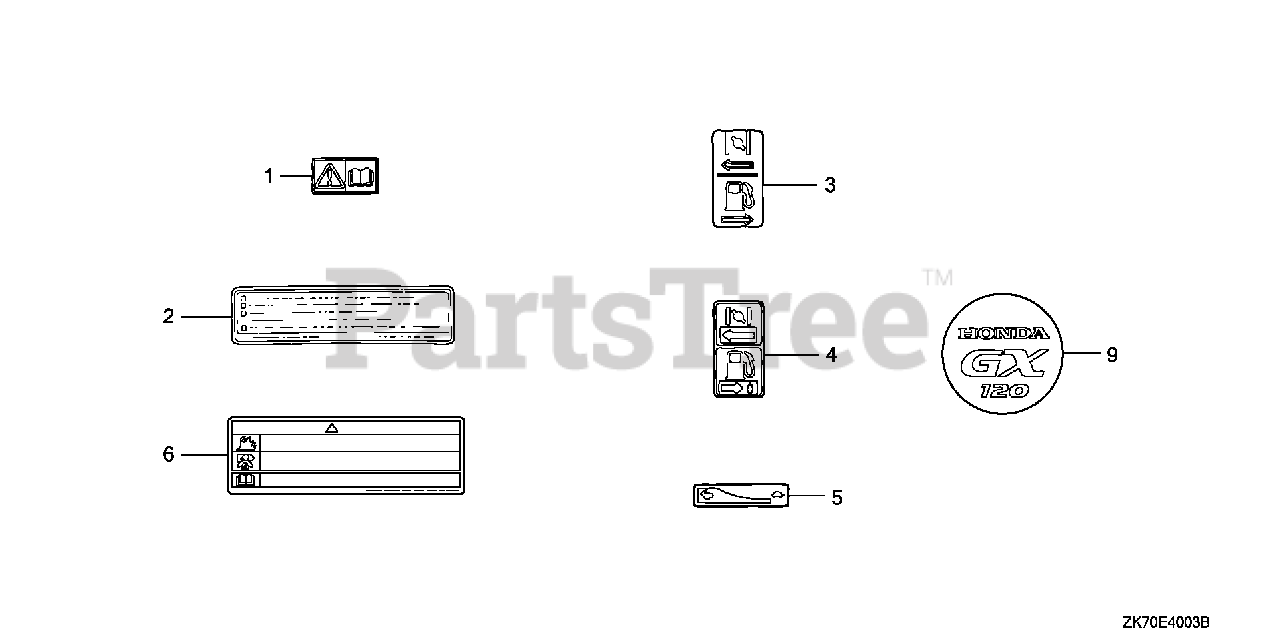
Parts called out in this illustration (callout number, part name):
1	MARK, CAUTION (PICTOGRAPH)
2	LABEL, CAUTION (ENGLISH, ETC.)
3	MARK, CHOKE
4	MARK, CHOKE (GRAY)
5	MARK, THROTTLE INDICATION
